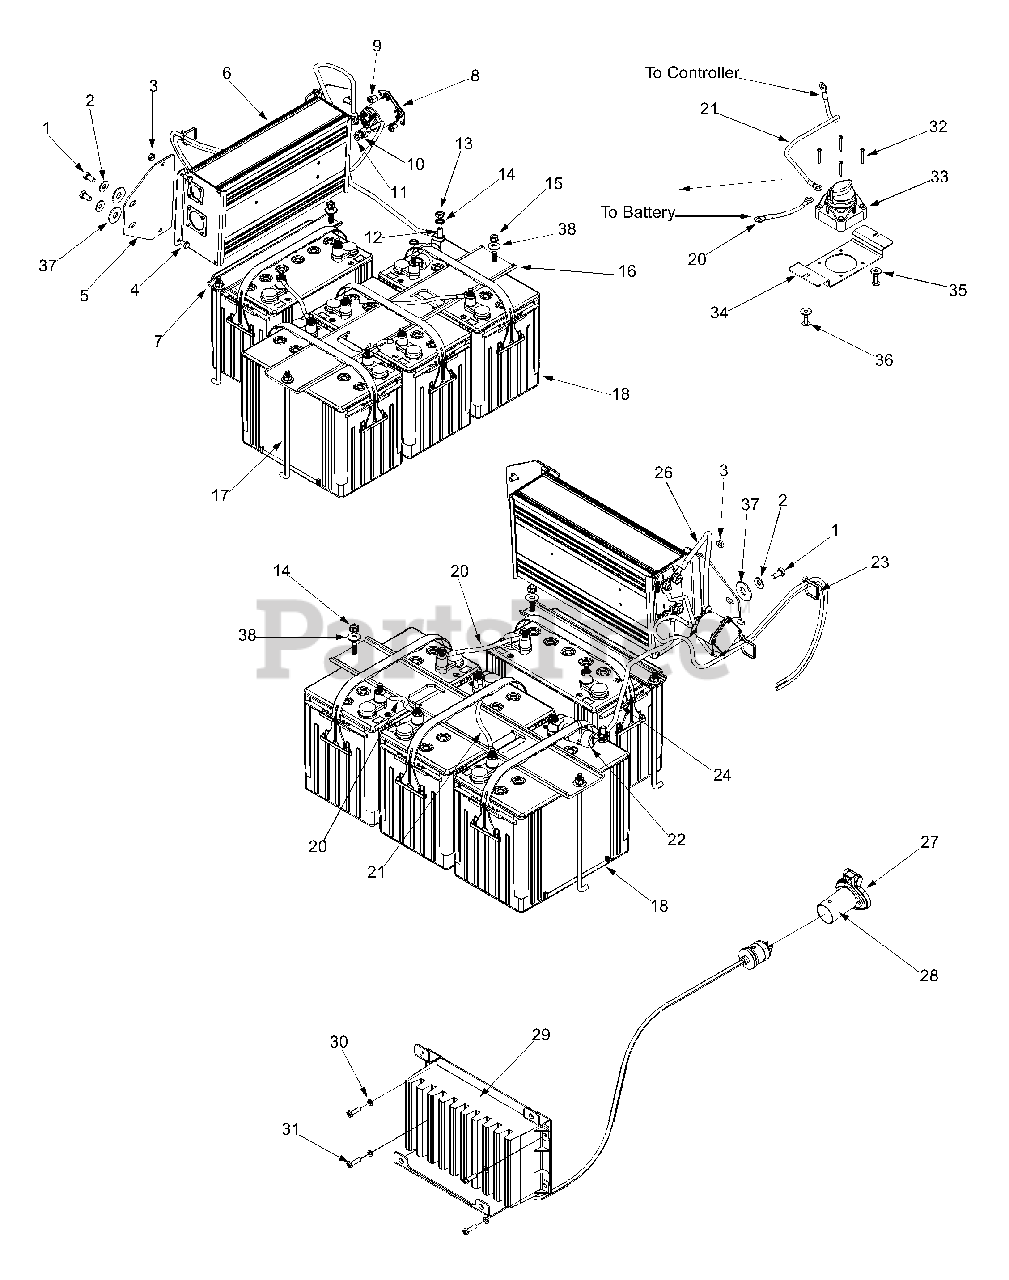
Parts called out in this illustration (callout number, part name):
1	Hex Cap Screw 5/16-24 x .750
2	Washer .330 ID x .630 OD
3	Hex Lock Nut 1/4-20
4	Hex Cap Screw 1/4-20 x .50
5	Controller Mounting Plate
6	Motor Controller Assembly
7	RR Battery Holddown Plate
8	Relay 100 amp
9	Machine Screw 1/4-20 x .500
10	External Lock Washer 5/16
11	Hex Nut 5/16-18
12	Hex Cap Screw 3/8-24 x .875
13	Jam Nut 3/8-24
14	External Lock Washer
15	Sems Nut 5/16-18
16	Battery Holddown Plate
17	L-Style Hook Bolt 5/16-18
20	Battery Harness Assembly
21	Battery Harness Assembly
23	Cable Tie
24	Battery Wire Harness
26	Relay Harness Assembly
27	Plug Housing
28	Plug Cover
29	Battery Charger
30	Bell Washer .265 ID x .75 OD
31	Machine Screw 1/4-20
32	Screw #6-32 x 1.25
33	Battery Reset Switch
34	Switch Plate
35	Bell Washer .265 ID x .75 OD
36	Machine Screw 1/4-20 x .625
37	Shoulder Spacer .317 ID x .385 OD
38	Washer .349 ID x .879 OD
